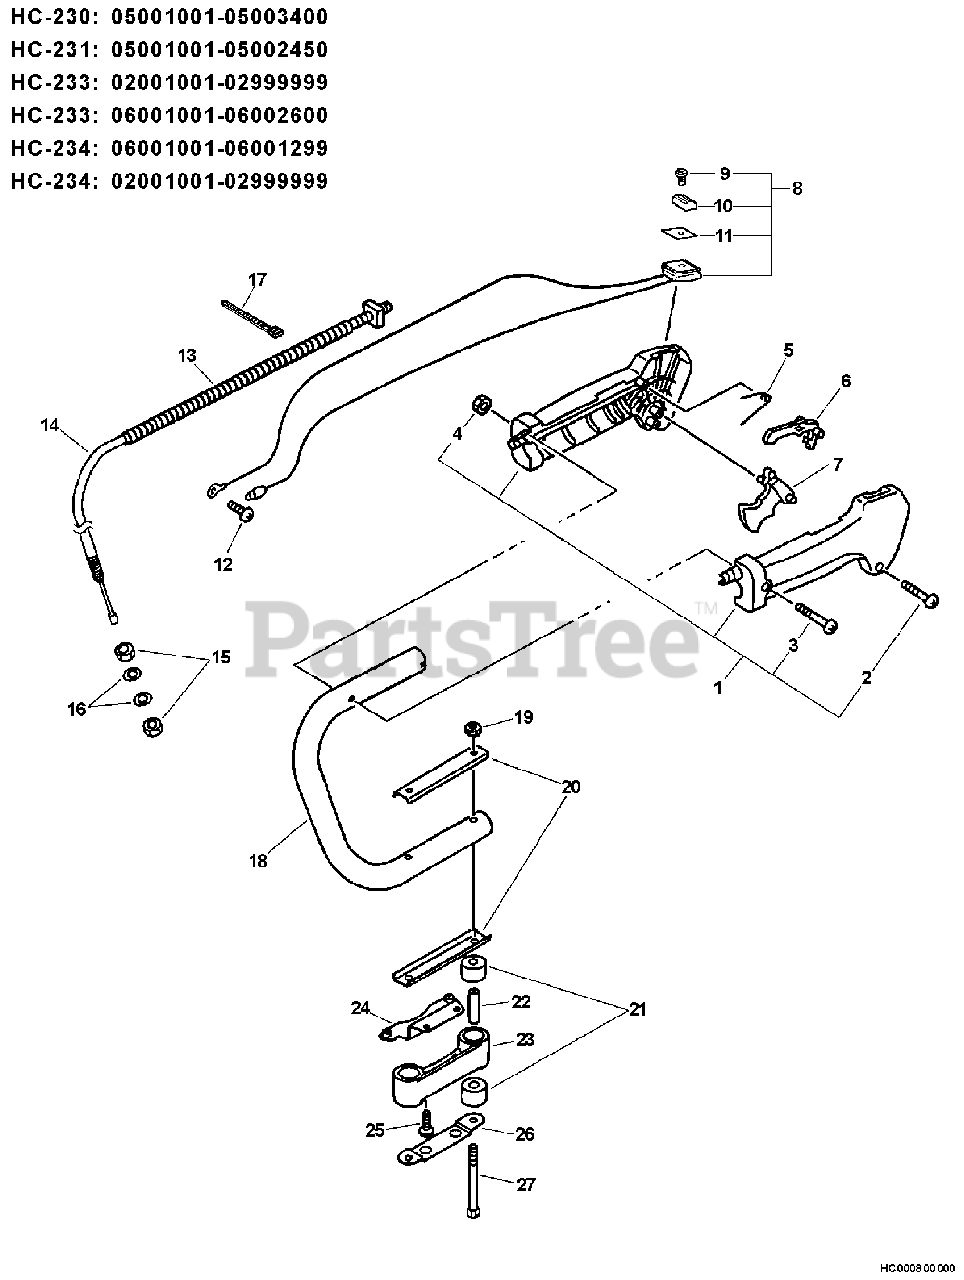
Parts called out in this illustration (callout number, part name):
1	THROTTLE CONTROL ASSY
2	SCREW - 3X25
3	SCREW - 5X30
5	SPRING, LOCKOUT LEVER
6	LOCKOUT, THROTTLE
7	TRIGGER, THROTTLE
8	IGNITION SWITCH ASSY
9	SCREW - 3X10
10	KNOB, SWITCH - ORANGE
11	COVER, SWITCH - STOP
12	SCREW - 5X10
13	TUBE, PROTECTIVE - CORRUGATED
14	CABLE, THROTTLE
16	WASHER - 6
17	TIE, CABLE
18	HANDLE - REAR
19	LOCKNUT - 5
20	BRACKET, HANDLE - LOWER
22	SPACER
23	BRACKET, HANDLE
25	SCREW - 5X16
26	PLATE, CUSHION
27	SCREW - 5X60
